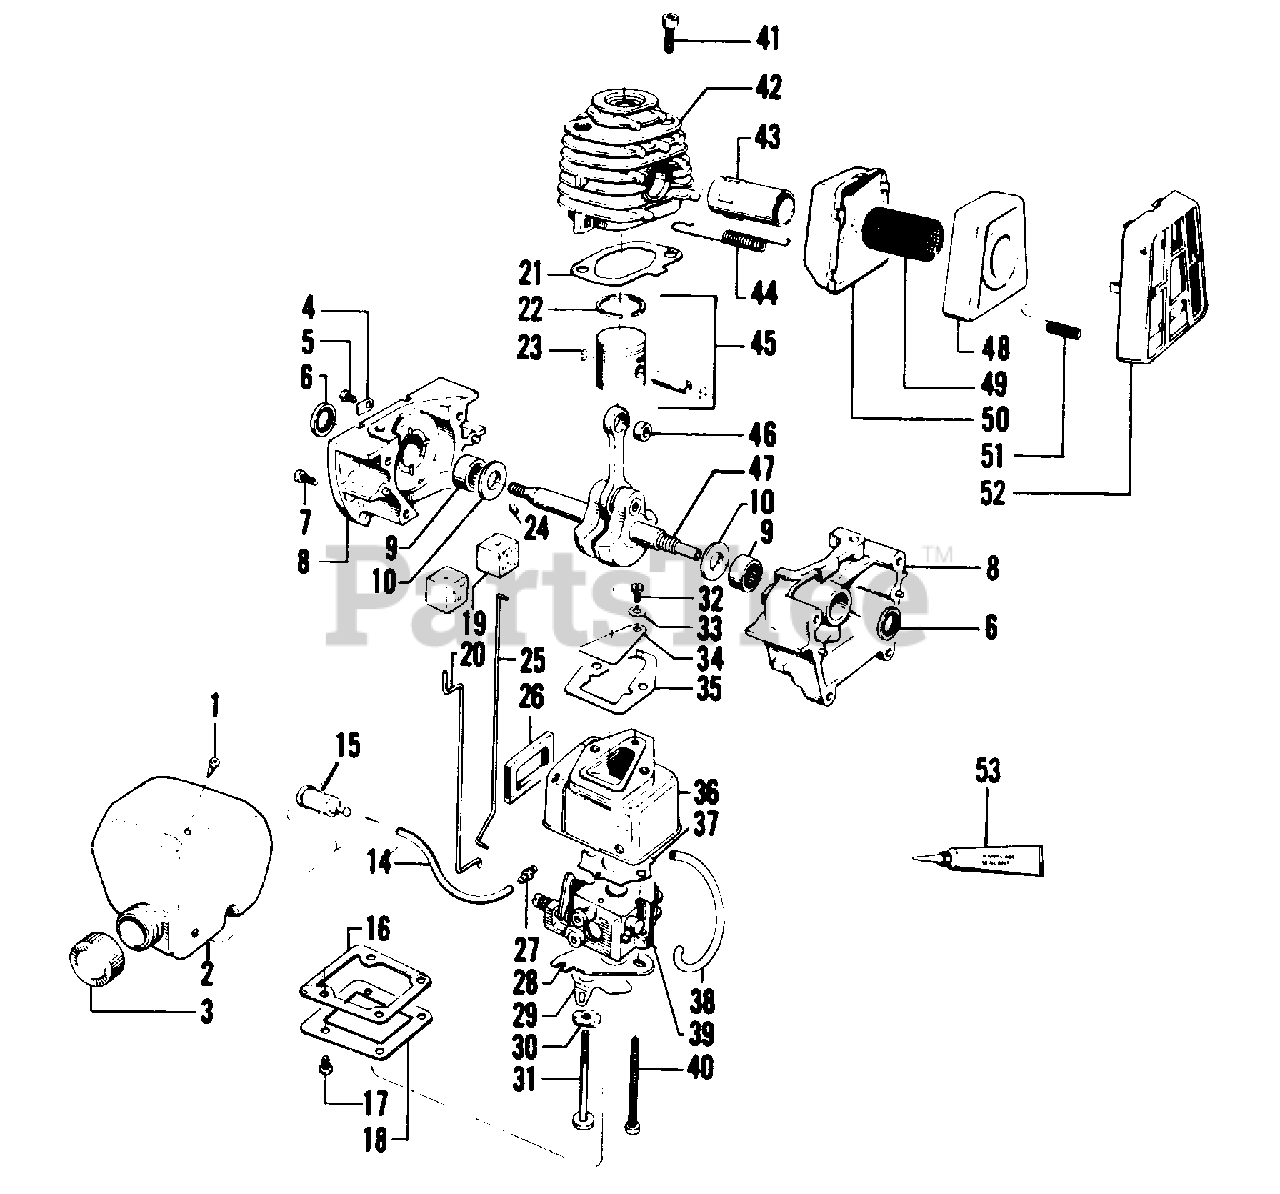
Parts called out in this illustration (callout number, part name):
1	Duck Bill Valve
2	Fuel Tank Ass'y. (Inc.1, 3 14 & 15)
3	Fuel Cap (Incl. O Ring)
4	Clamp - Choke Wire
5	Screw - #8 - 32 x 5/16" - Choke Rod Clamp
6	Seal - Crankshaft
7	Screw - #10 - 24 x 5/8" - Crankcase
8	Crankcase Assembly (Inc.6, 9 and Qty. 4 of #7)
9	Bearing - Crankshaft
10	Washer - Crankshaft Thrust
14	Fuel Line
15	Fuel Pick-Up Ass'y.
16	Gasket - Carburetor Case Cover
17	Screw - #8 - 18 x 9/16" - Carburetor Case Cover
19	Boot - Throttle - Choke Wire
21	Gasket - Cylinder
22	Piston Ring
23	Retainer - Wrist Pin
24	Key - Flywheel
25	Throttle Wire
26	Seal - Carburetor Case
27	Fuel Line Fitting
29	Choke Shutter
30	Wave Washer
31	Screw - #10 - 24 x 2-1/8" - Carburetor - Shoulder
32	Screw - #10 - 24 x 2-1/8" - Reed Valve
33	Washer - # 6 - Reed Valve Screw
34	Reed Valve
35	Gasket - Carburetor Case to Crankcase
36	Carburetor Housing
37	Carburetor Gasket
38	Fuel Line - Carburetor
39	Carburetor - See Service Ref. 2.
40	Screw - #10 - 24 x 1-7/8" - Carburetor
41	Screw - #1/4 - 20 x 3/4" - Cylinder
42	Cylinder
43	Diffuser - Muffler
44	Spring - Muffler Attachment
45	Piston Assembly (Inc. 22, 23 & Pin)
46	Bearing - Wrist Pin
47	Crankshaft & Rod Assembly
48	Body Muffler
49	Screen - Spark Arresting
50	Cover Muffler
51	Spring - Muffler Guard
52	Guard - Muffler
53	Sealant - Crankcase (not supplied)
